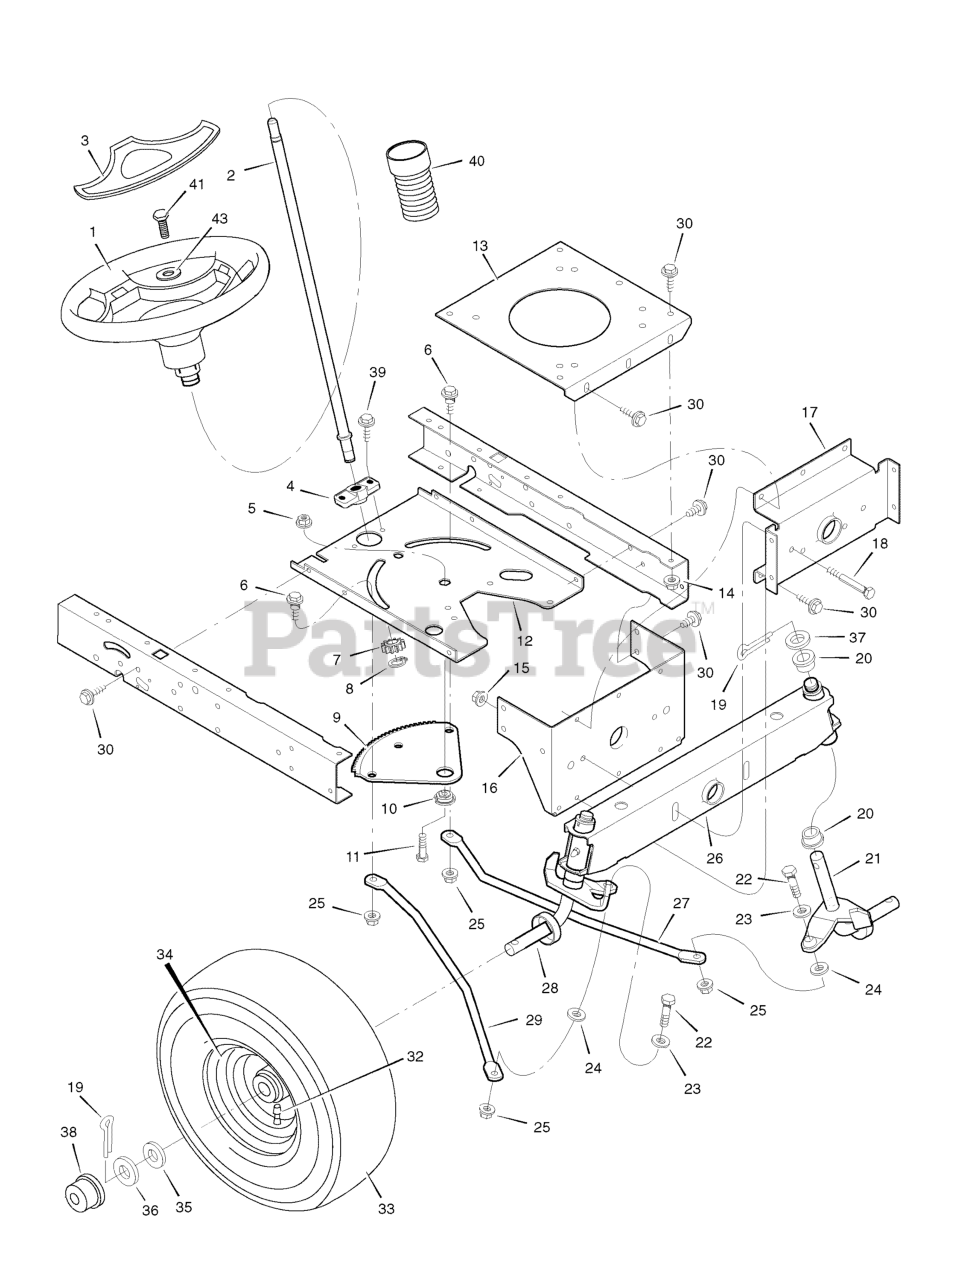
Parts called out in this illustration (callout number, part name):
1	WHEEL, Steering
2	POST, Steering
3	COVER, Steering Wheel
4	Bearing
5	Nut, Flange **
6	BOLT, Shoulder
7	GEAR, Pinion **
8	Ring, Snap **
9	GEAR, Sector
10	BEARING
11	CAPSCREW, Hex Head, 5/16-18 x 1
12	PLATE, Steering
13	PLATE, Engine
14	NUT, Flange
15	NUT, Flange
16	BRACKET, Hanger
17	AXLE, Hanger
19	PIN, Cotter
20	BEARING
21	SPINDLE ASSEMBLY, Left
22	BOLT
23	WASHER
24	WASHER
25	NUT, Flange
26	AXLE ASSEMBLY
27	DRAG LINK ASSEMBLY, Left
28	SPINDLE ASSEMBLY, Right
29	DRAG LINK, Right
32	STEM, Valve
34	WHEEL & TIRE ASSEMBLY
38	HUB CAP
40	BELLOWS
41	Screw, Hex
43	WASHER
